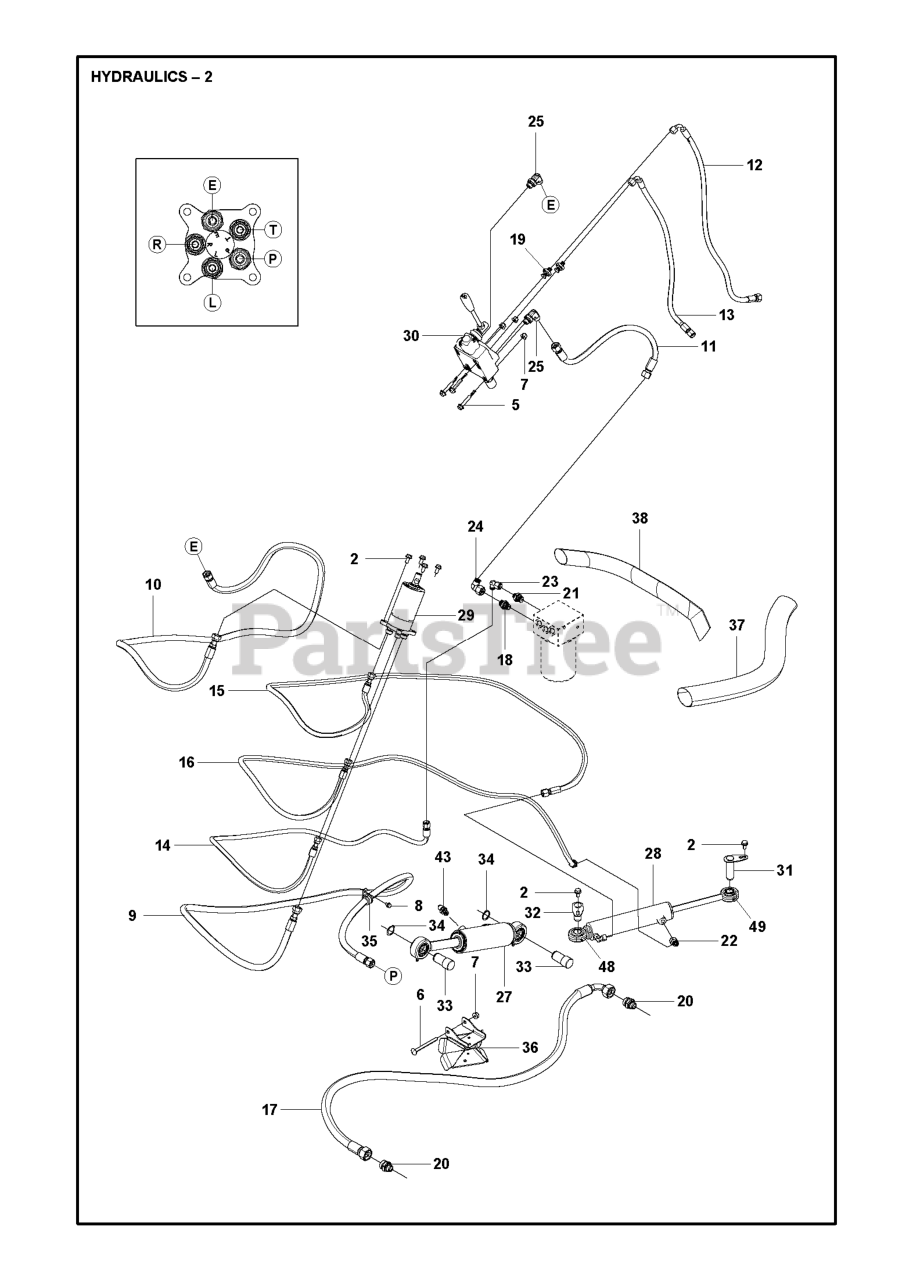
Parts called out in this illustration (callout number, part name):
7	NUT FLANGE
34	RETAINING RING SGA 25
35	HOSE CLAMP
